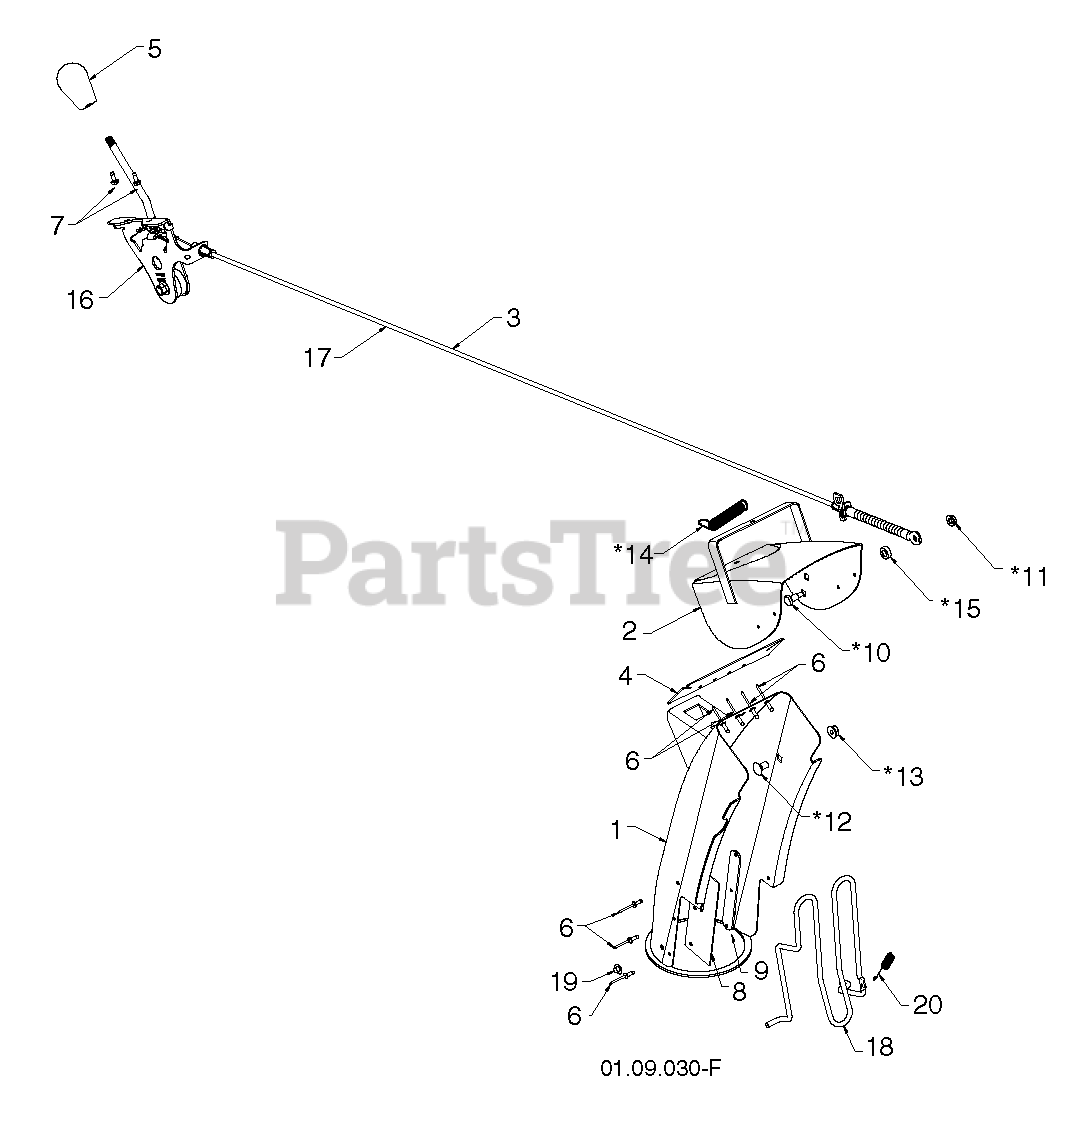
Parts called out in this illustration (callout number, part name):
1	ASM.CHUTE/DEFLECTOR.668
3	RP CABLE.DEFLECTOR.CONTRL.BOWD
5	KNOB.OVERMOLD.DS.HUSQVARNA/BLK
10	BOLT.CARR.W.3125 SHLDR..25-20
11	NUT.HEX.FLANGE.1/4
12	BOLT CAR BLK 5/16-18 X 5/8
13	LOCKNUT-FLANGE 5/16-18
14	SPRING.DEFLECTOR.REM.CHUTE
15	WASHER.NYLON.326 X.625 X.205
16	RP CNTRL.HEAD.ASSEM.DEFLECTOR
17	RP CABLE.DEFLECTOR.CONTRL.BOWD
18	ROD.GUARD.CHUTE (2 2)
19	NUT
20	SPRING.CHUTE.GUARD
